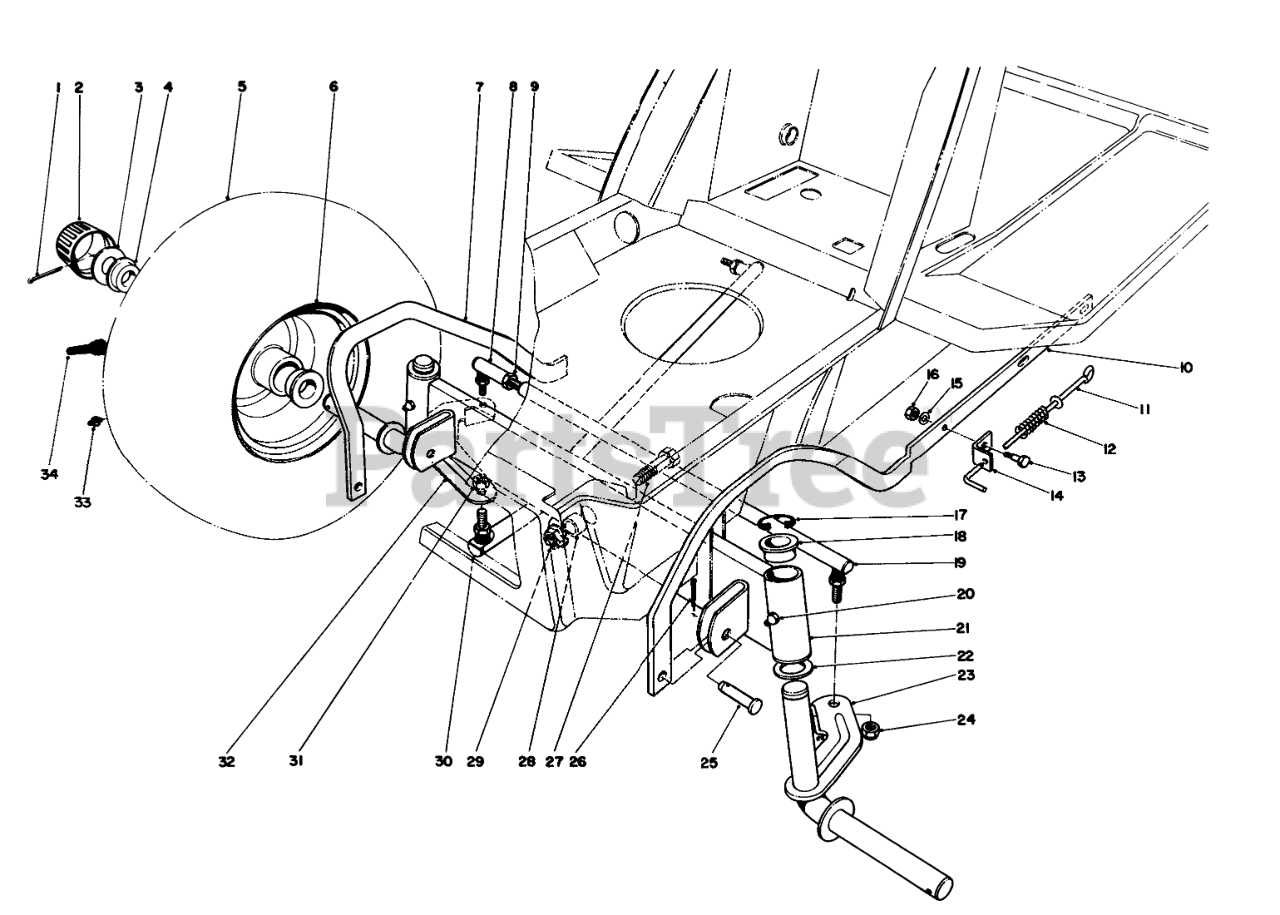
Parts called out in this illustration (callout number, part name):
1	PIN-COTTER
2	CAP-HUB
3	WASHER-PLAIN
4	Bearing
5	FRONT TIRE
6	FRONT RIM
7	Scissors Link-R.H.
8	JOINT-BALL
9	NUT-JAM
10	Scissors Link-L.H.
11	Pin-Tension
12	COMP SPRING
13	Bolt-Shoulder
14	TENSION BELT BRKT B
15	WASHER-PLAIN
16	NUT-LOCK, CONE
17	E-RING
18	BEARING-FLANGE
19	Tie Rod-Steering (Incl. Ref. #8 & 9)
20	GREASE FITTING
21	Front Axle (Incl. Ref. #18)
22	WASHER-THRUST
23	LH SPINDLE WA PP
24	NUT-LOCK, NI
25	PIN-CLEVIS
26	PIN-COTTER
27	SCREW-HH
28	SPACER-AXLE, FRONT
29	NUT-HF
30	STEERING ARM B
31	NUT-HEX
32	RH SPINDLE WA PP
33	FITTING-GREASE
34	STEM-VALVE
